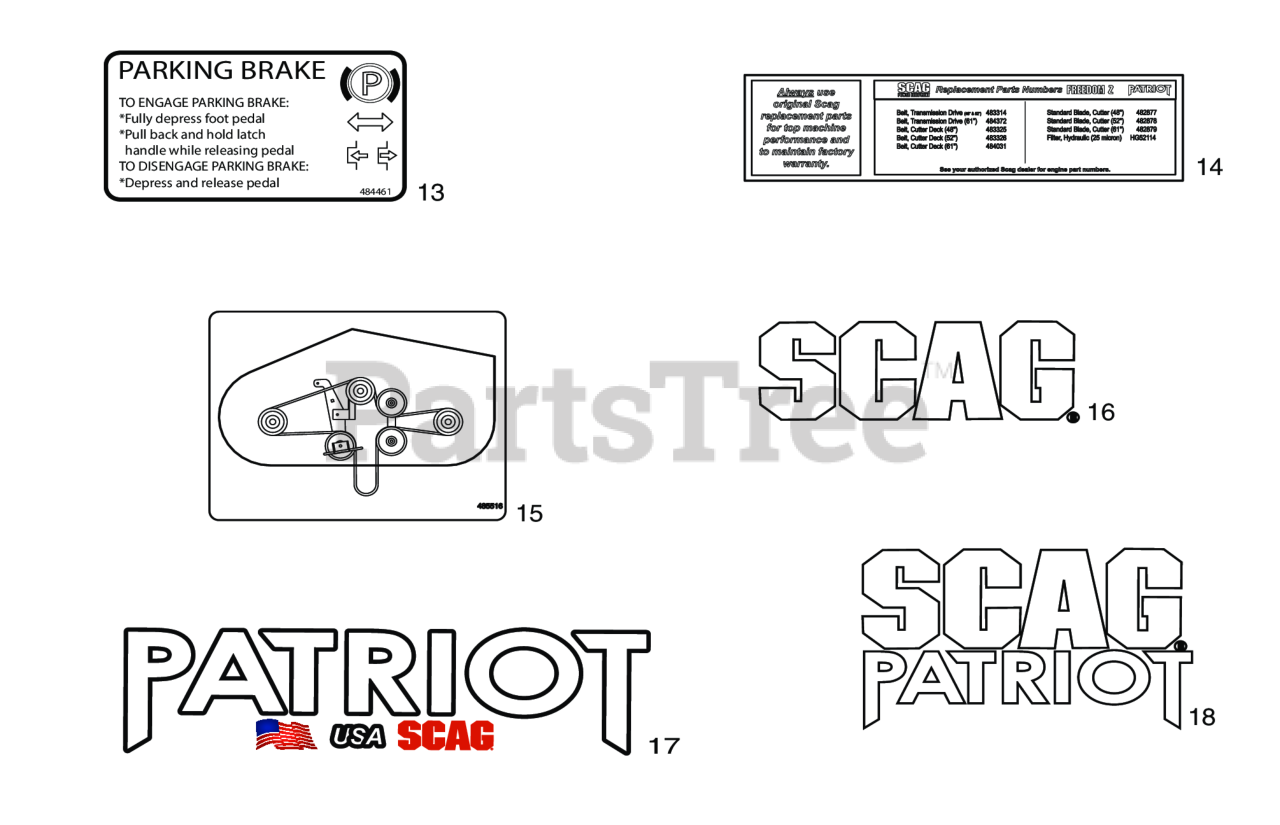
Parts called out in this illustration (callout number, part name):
13	Decal, Brake
14	Decal, SFZ / SPZ Replacement Parts
15	Decal, SZL / SFZ / SPZ Belt Routing
16	Decal, Scag - Fuel Tank
17	Decal, Patriot, (Scag Gold Logo) - Fuel Tank
18	Decal, Scag Patriot, (Scag Gold Logo) - Fuel Tank
